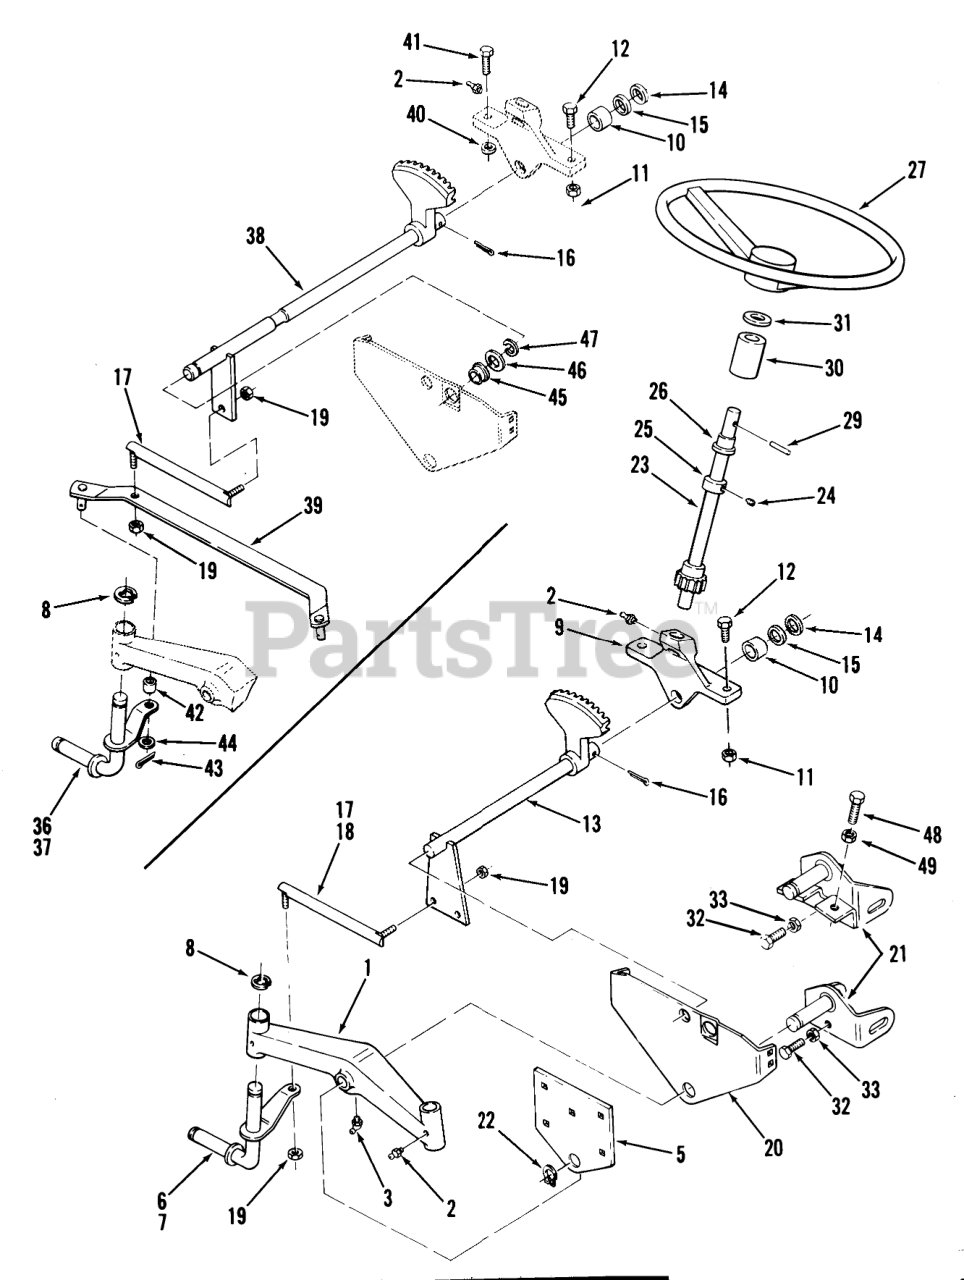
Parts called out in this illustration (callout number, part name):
1	AXLE-FRONT R
2	Zerk
3	FITTING-GREASE
5	PLATE-FRONT AXLE R
6	Assy-Front Spdl RH
7	Assy-Front Spdl LH
8	Snap Ring
9	Support
10	BEARING-BRONZE
11	Nut
12	Bolt
13	ASSY-STRG SHFT LO R
14	WASHER-SHIM
15	WASHER
16	PIN-4
17	25LL JOINT ASSY R R
18	BALL JOINT ASSY L R
19	NUT-6
20	Support Front Axle
21	Front Hanger (Mower)
21	ASSY-FRONT HANGER R
22	Snap Ring
23	ASSY-STEER SHFT U R
23	ASSY-STRG SHFT-UP R
24	SCREW-SET
25	Collar
26	BEARING
27	STEERING WH 13" PLAS
29	Pin-Roll
30	Collar
30	COLLAR
31	WASHER-BOWED
32	SCREW-HH
33	Nut
36	Assy-Front Spdl RH B-165 Only
37	Assy-Front Spdl LH B-165 Only
38	Assy Strg Lower B-165 Only
39	ASSY-TIE ROD R
40	WASHER
41	BOLT
42	SPACER
44	WASHER
45	BUSHING
46	WASHER SPECIAL
47	Ring
48	Bolt
49	Nut
